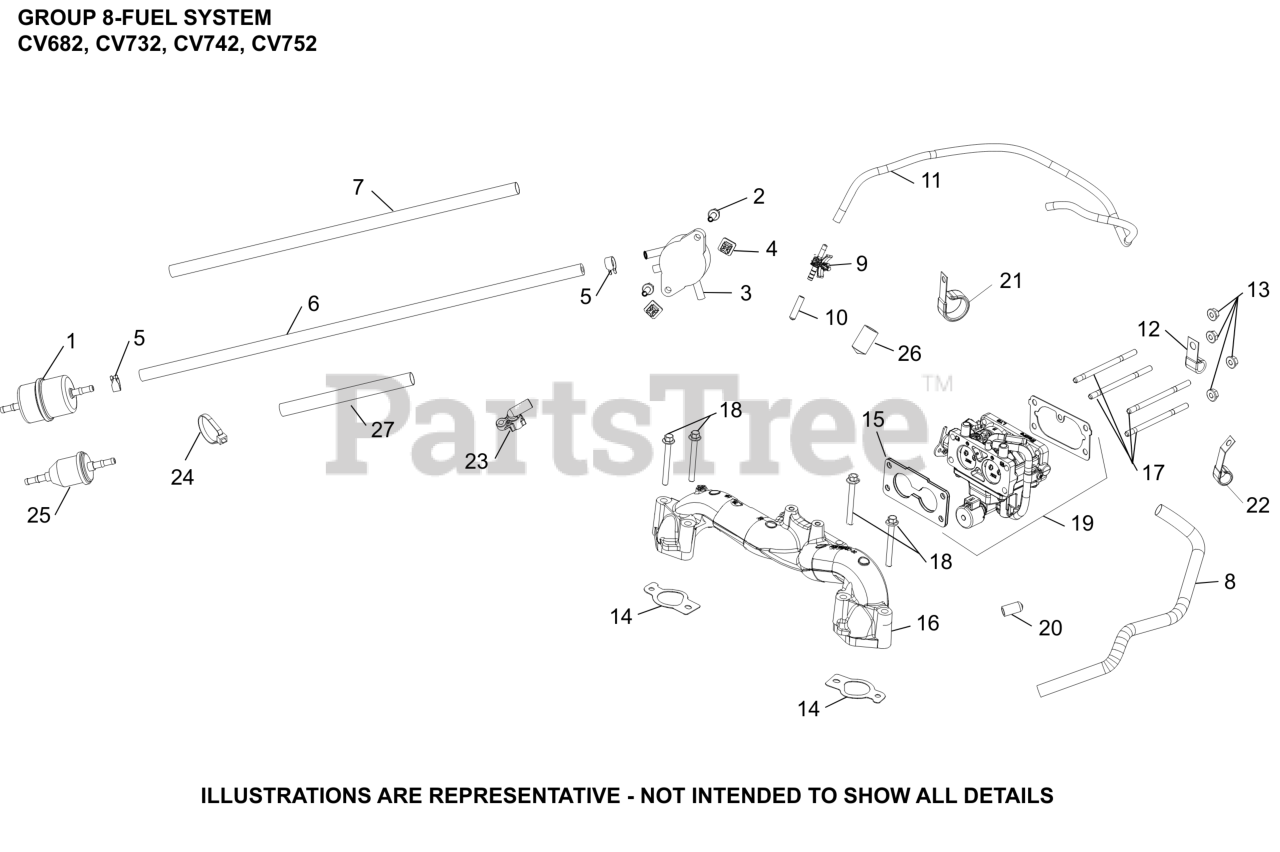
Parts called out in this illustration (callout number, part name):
1	FILTER, FUEL
3	PUMP, FUEL
4	NUT, PLASTIC - BLACK
5	SPRING CLAMP, HOSE
6	HOSE,LW PERM.FUEL 24.00"-USE 25 111 81-S
8	SLEEVE, INSULATING 14"
8	SLEEVE, ANTI-ABRASION
9	CONNECTOR, EVAPORATIVE
10	CAP, MASKING
11	HOSE, EVAPORATIVE
13	NUT, FLG M6X1.0
14	KIT, INTAKE MANIFOLD GASKET
15	GASKET, CARBURETOR
16	KIT, MANIFOLD INTAKE (VERTICAL 2BBL)
17	STUD,M6X1.0X96
18	SCREW, HEX FLANGE
NI	SCREW, HEX HEAD
